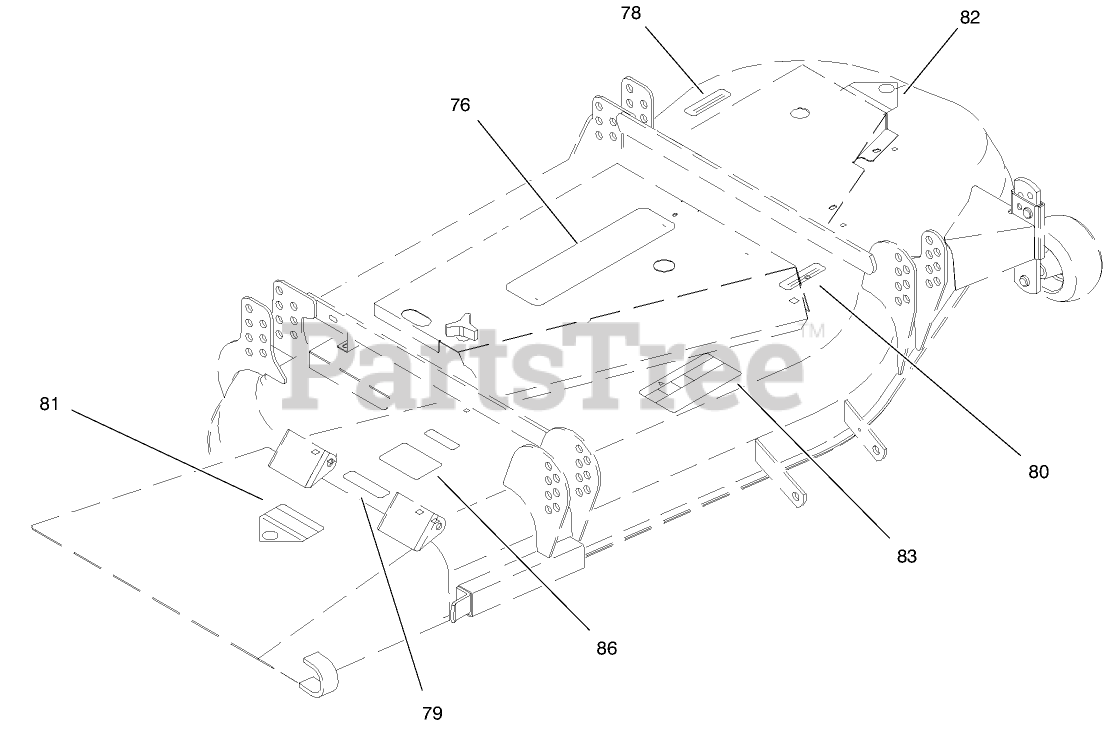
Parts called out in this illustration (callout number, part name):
76	DECAL
78	DECAL-TORQUE
79	DECAL-DANGER
80	DECAL-DANGER
81	DECAL-DANGER
82	DECAL-DANGER
83	DECAL-DANGER, THROWN OBJECT
86	DECAL
